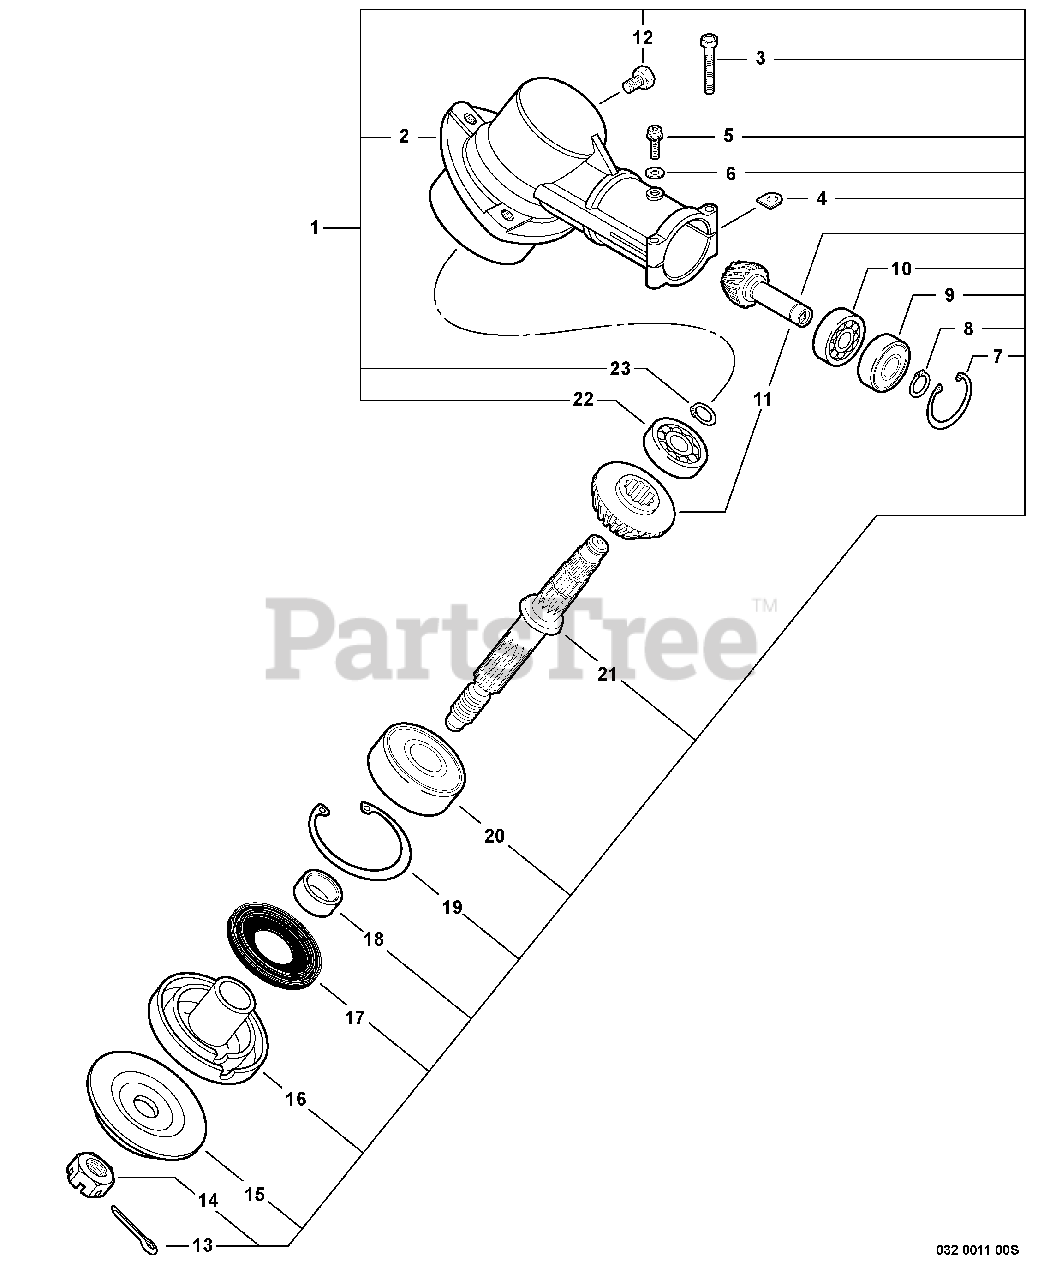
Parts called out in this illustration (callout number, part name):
1	GEAR CASE ASSY
2	CASE, GEAR
3	BOLT - 5X35
5	SCREW - 5X10
6	WASHER - 5
7	RING, RETAINING - 22
8	RING, RETAINING - 10
9	BEARING, BALL - 6900Z
10	BEARING, BALL - 6900
11	GEAR SET - BEVEL
12	BOLT - 8X8
13	PIN, SPLIT - 2X22
14	NUT - 10 -- LEFT HAND
15	ADAPTOR, BLADE - LOWER
16	ADAPTOR, BLADE - UPPER
17	SEAL, OIL
19	RING, RETAINING - 32
20	BEARING, BALL - 6201
21	GEAR - SHAFT
22	BEARING, BALL - 609
23	RING, RETAINING - 12
